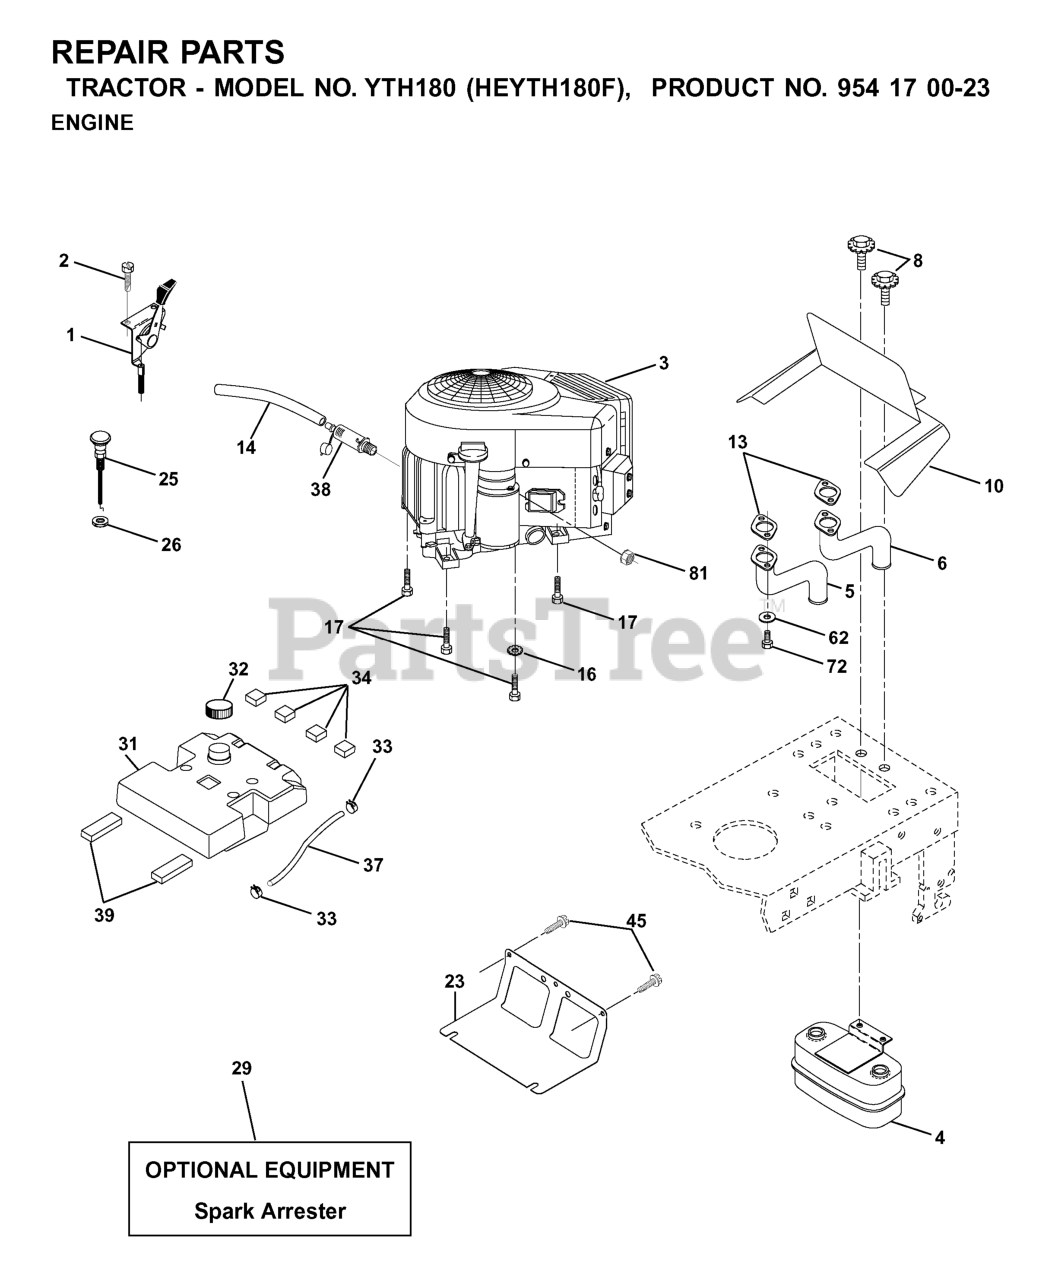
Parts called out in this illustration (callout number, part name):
1	CONTROL, THROTTLE
2	SCREW LT
4	MUFFLER.TWIN.CYL.LOW.TONE
5	RP.EXHAUST.TUBE.LH.BS/TWIN
6	EXHAUST.TUBE.RH.BS/TWIN
8	BOLT.5/16-18UNCX3/4 W/SEMS.BLK
10	SHIELD.BROWNING.B&S
13	GASKET.MUFFLER
14	TUBE, DRAIN OIL ASM.
16	LOCKWASHER
17	SCREW LT
23	SHIELD.BROWNING.DBR.GUARD
25	CONTROL, CHOKE
26	Nut Keps 3/8 - 24 UNF
29	KIT.SPARK ARRESTOR 794945 B&S
31	TANK.FUEL(3.5.GAL)
32	FUEL CAP
33	HOSE CLAMP
34	PAD-SPACER LT
37	HOSE T
38	PLUG, OIL DRAIN EASY
39	PAD IDLER TI
45	SCREW, 3/8-16X3/4
62	WASHER.LOCK.HVY.HLCL.SPR.5/16
72	SCREW
81	NUT
